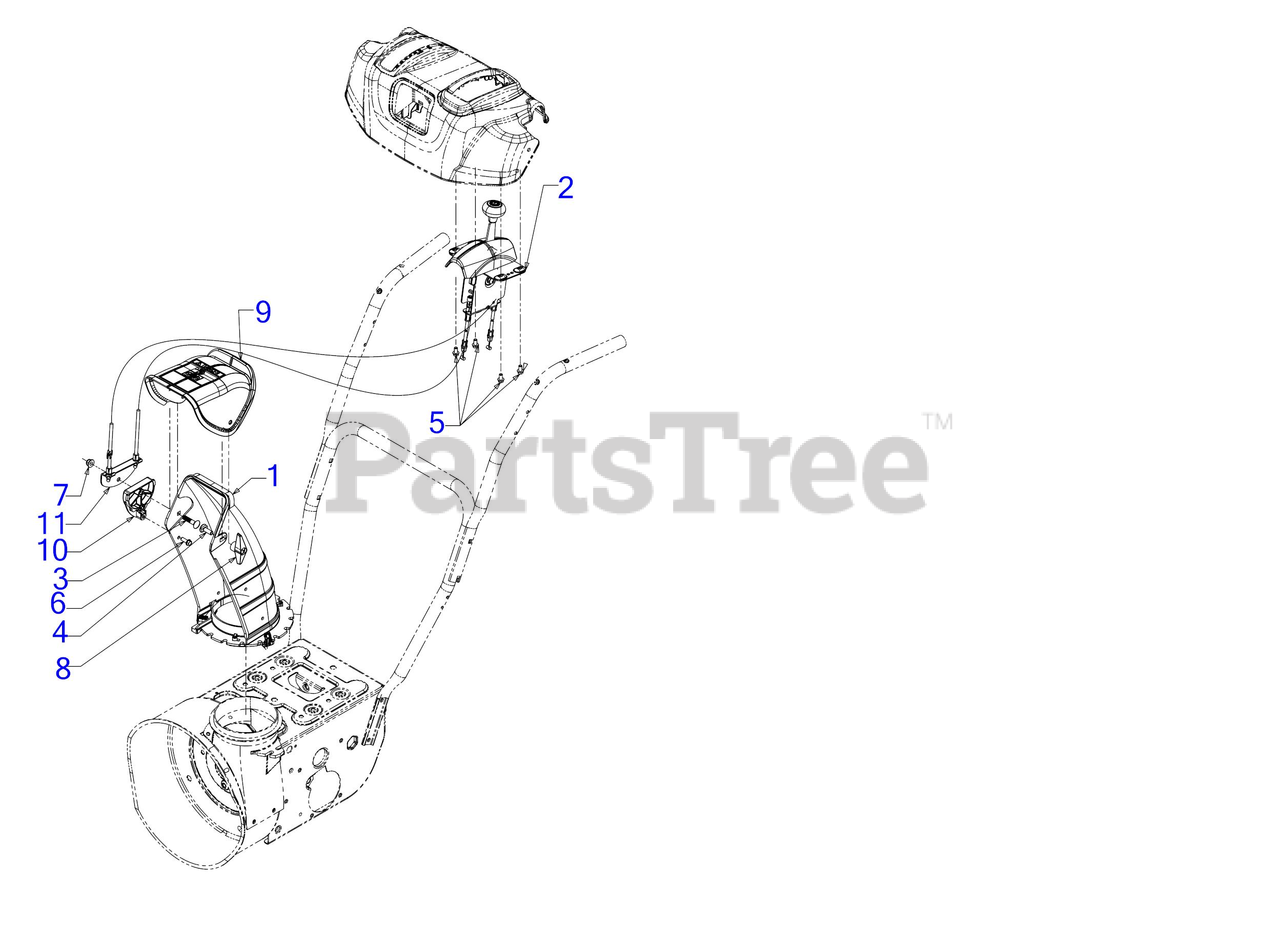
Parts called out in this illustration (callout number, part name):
1	2-WAY LOWER CHUTE ASSEMBLY
2	CHUTE CONTROL
3	CARRIAGE BOLT 5/16-18 x 1.50
4	CARRIAGE BOLT 5/16-18 x 1
5	HEX SCREW 1/4-15 x .50
6	SCREW 1/4-15 x .750
7	FLANGE LOCK NUT 5/16-18
8	WING NUT KNOB
9	UPPER REMOTE CHUTE WITH LABEL
10	CABLE GUIDE
11	CABLE BRACKET
